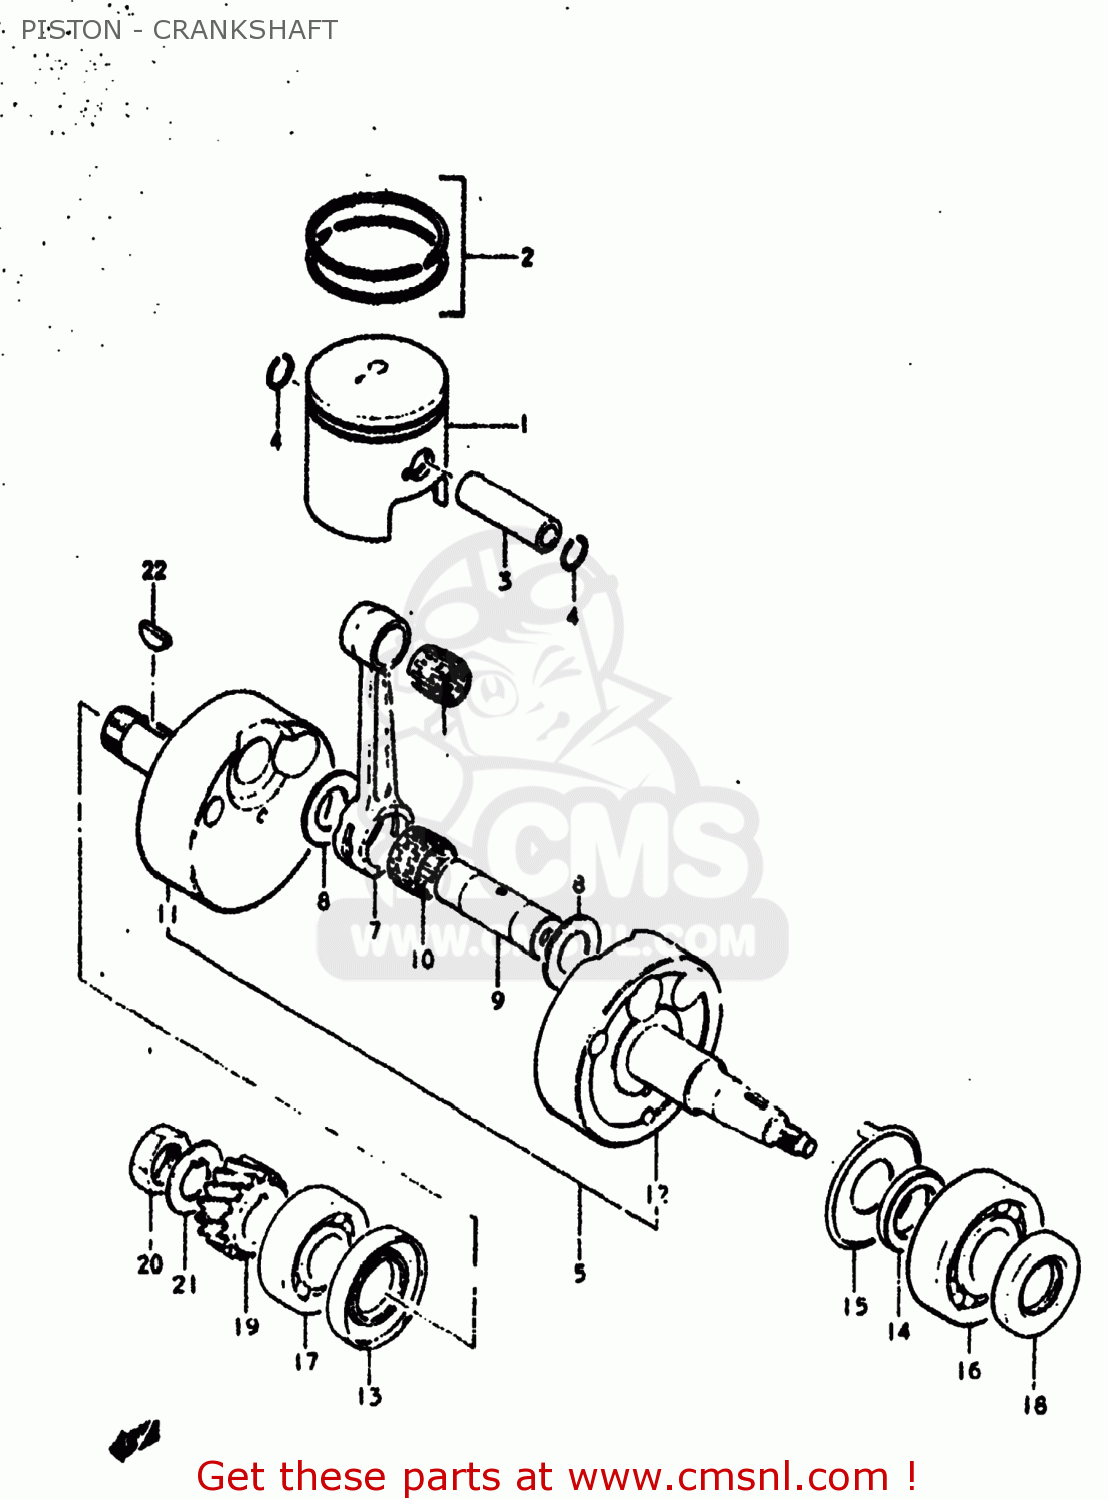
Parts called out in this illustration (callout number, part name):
1	PISTON
2	RING SET,PISTON
3	PIN,PISTON
4	RING,SNAP 14MM
5	CRANKSHAFT ASSEMBLY
6	BEARING
7	CONNECTING ROD
8	WASHER(19X32X1)
9	PIN,CRANK
10	BEARING
11	CRANKSHAFT
12	CRANKSHAFT,LEFT
13	SEAL,OIL(26X52X8)
14	SPACER
15	PLATE,CRANKSHAFT OIL GUIDE
16	BEARING(25X62X17)
17	BEARING
18	OIL SEAL
19	GEAR,PRIMARY DRIVE
20	NUT
21	WASHER
22	KEY
